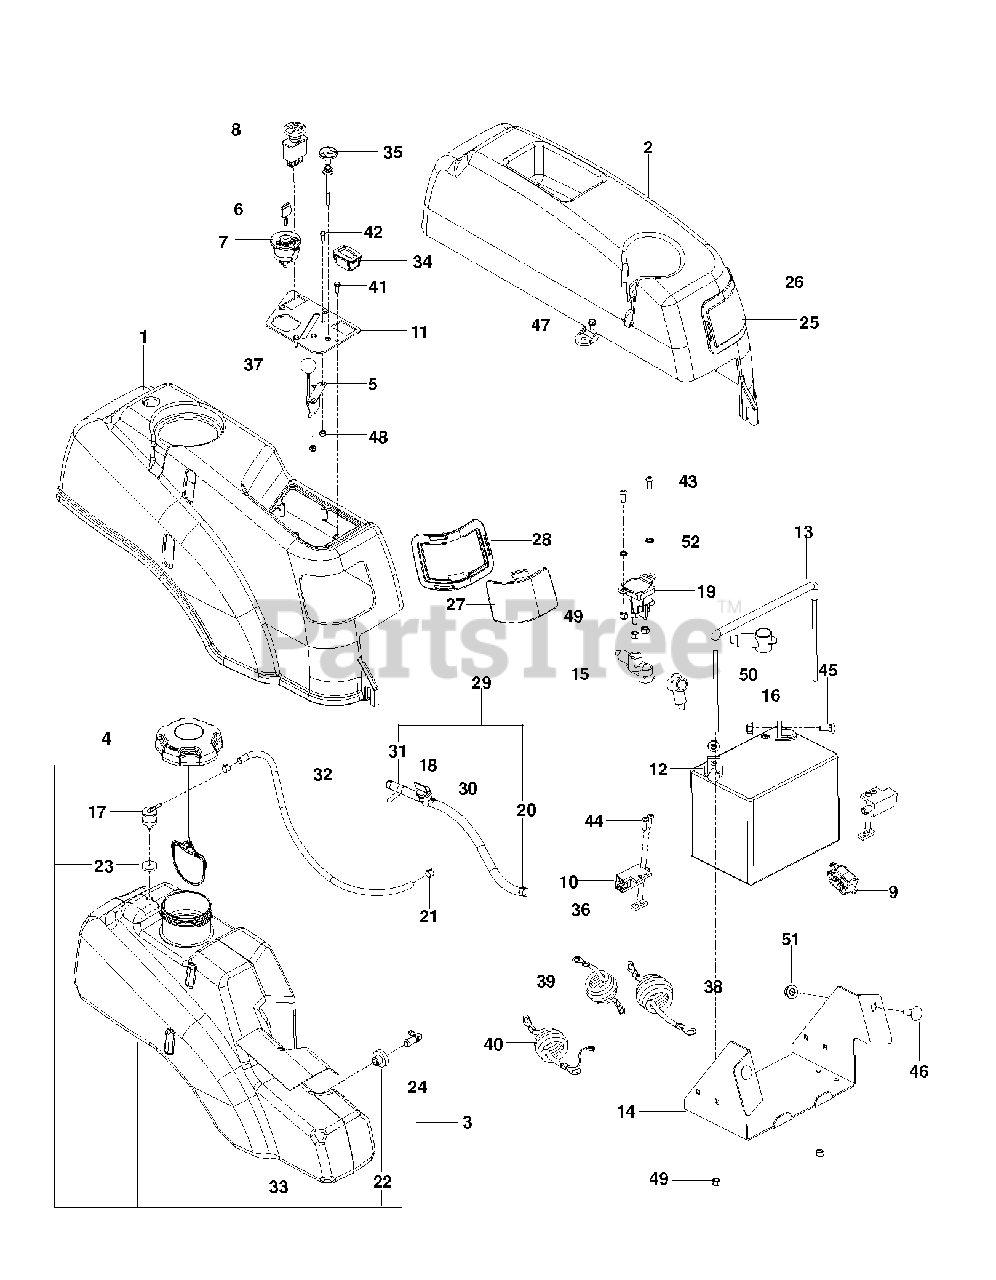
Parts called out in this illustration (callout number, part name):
1	FENDER RT, BLACK
2	FENDER, LT, BLK
3	FUEL TANK ASM, LARGE
4	CAP, FUEL
5	THROTTLE CABLE
7	IGNITION SWITCH
9	SWITCH, BRAKE 3P
13	BATTERY TIE DOWN ASSEMBLY
14	BOX, BATTERY, BLACK
15	TERMINAL COVER-SM
16	INSULATOR
17	VALVE.FUEL.CHECK
18	FUEL VALVE
19	SOLENOID
20	HOSE CLAMP
21	CLAMP, HOSE
22	RUBBER GROMMET
23	GROMMET, CHECK VALVE
25	PANEL, LT
26	RING, LT BLK
27	PANEL, RT, BLK
28	RING, TRIM, RT-BLK
29	FUEL LINE ASSY
30	GAS LINE 10"
31	FUEL LINE 2.5"
32	HOSE, FUEL, 3/16" X 20"
35	CHOKE CABLE
36	TAPPED PLATE
37	KNOB ROUND BALL
38	CABLE POSITIVE, LONG
39	BATTERY CABLE, NEGATIVE
41	SCR #10-12X3/4 HEX WAS HD ZD
42	HCS #10-24 X 1/2
43	SCR 1/4-20 X 5/8 BTN SKT HD ZD
44	SCR #10-24 X .75 SKT HD BLK
45	BOLT 5/16C X 3/4" CARRIAGE
46	RHSNB 3/8C X 1
47	WASHER 3/8 SAE FLAT
48	NUT 10-24 NYLOC
49	NUT 1/4-20 NYLOC
50	5/16-18 NYLOC FLANGE NUT
51	NUT 3/8-16 HEX FLG NYLOC ZD
52	WASHER 1/4 INT TOOTH
